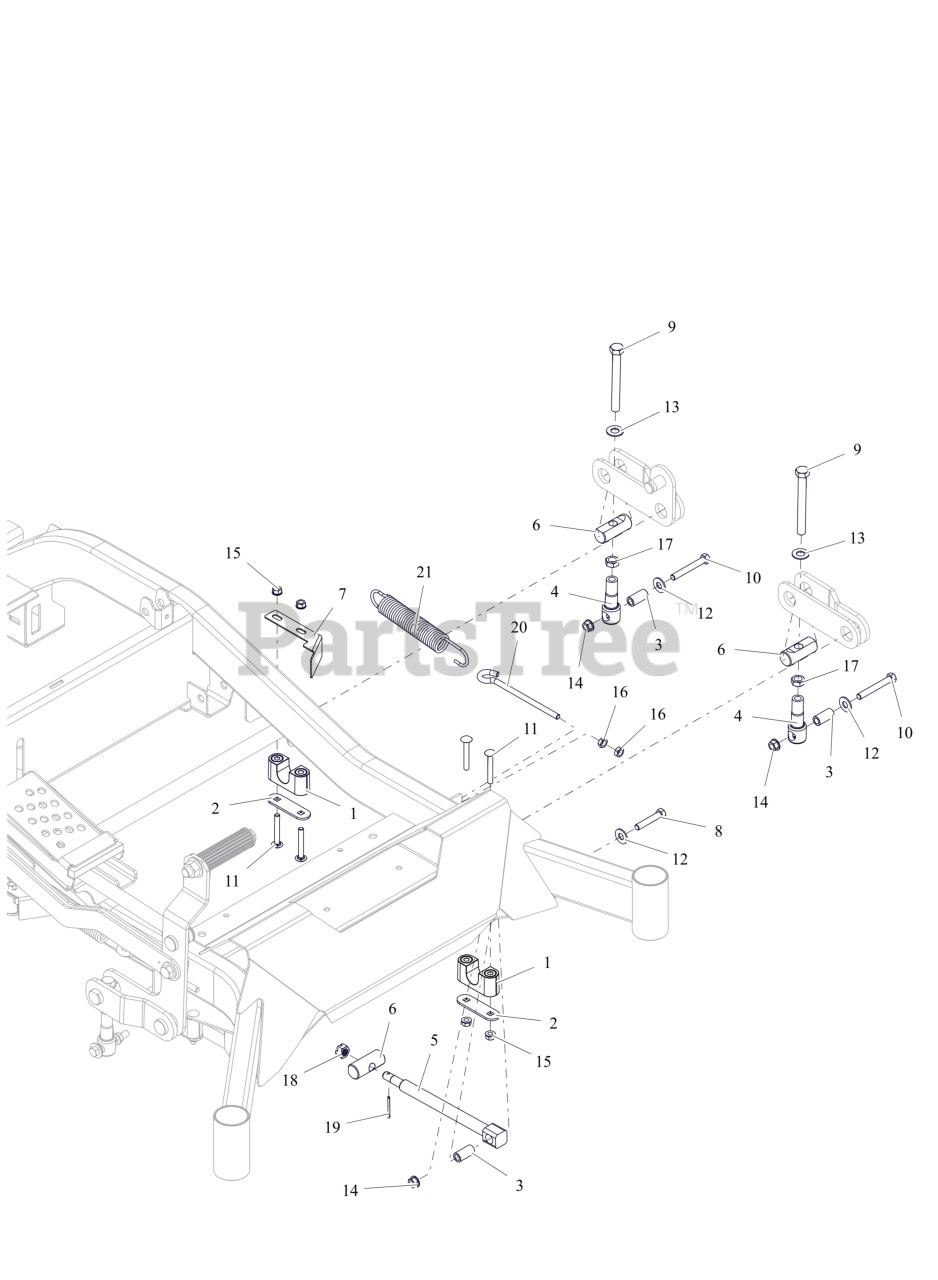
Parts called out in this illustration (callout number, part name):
1	ASM-BUSHING, DECK LIFT
2	PLATE, BEARING SUPPORT
3	SPACER, DECK LEVELING
4	LINK, DECK LIFT FORMED
5	DRAG,LINK-HD
6	PIN, DECK LIFT
7	GUARD, STOP CE 60 (BLACK)
8	BLT,HEX .38-16X2.00 G5 ZCC
9	BLT, HEX .50-13X4.50F G8 ZCC
10	BLT, HEX .38-16X2.75 G8 ZCC
11	BLT, RHSSN.31-18X2.25 G5 ZCC
12	WSHR,FLT .438X1.00X.083 ZCC
13	WSHR, FLT .557X1.040X.102 ZCC
14	NUT-LK-TOP-FLG .38-16 ZC120
15	NUT,LK-CTR-FLG .31-18 GF ZCC
16	NUT-JAM .375-16 G2 ZCC
17	NUT-JAM .500-13 G2 ZCC
18	NUT-SL .50-13
19	PIN,CTR.12X1.25EXTPRSQCT ZC120
20	BOLT,.38-16 X 5.25-.62 DIA EYE
21	SG-TENS .162X1.25X8.25 WLD 25
